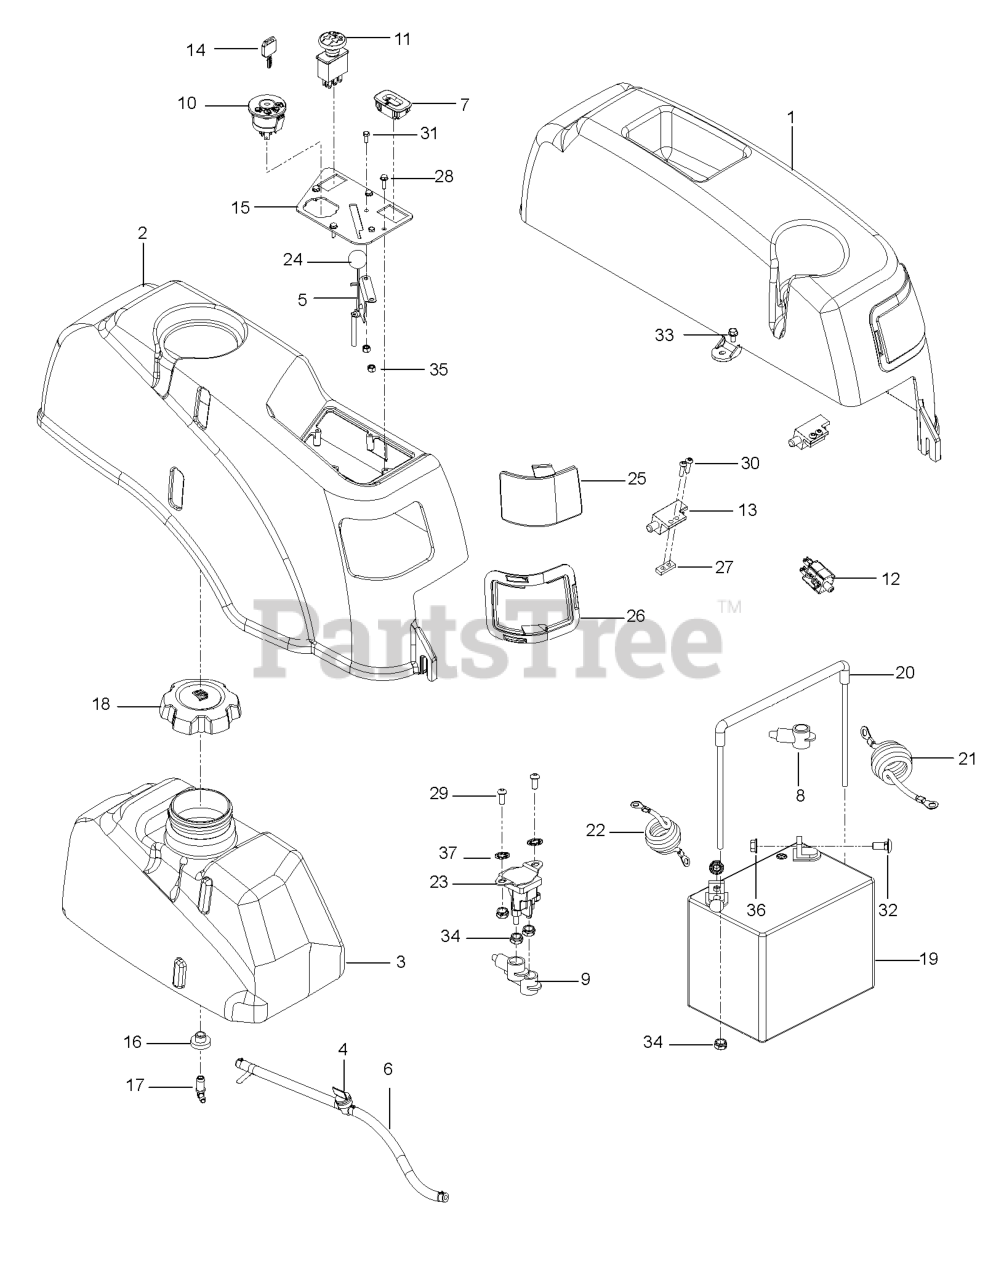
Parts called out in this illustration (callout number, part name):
1	FRAME WELDMENT, ORANGE
2	CHAIN COVER, ORANGE
3	BEARING SUPPORT, ORANGE
4	BUSHING, FLANGED
5	BEARING, FLANGED
6	HCS 5/16C X 3/4
7	HCS 5/16C X 1 1/4
8	NUT 5/16 NYLOC
9	OIL CAP, 3/8"
10	HCS 3/8C X 1 1/4 GR5
11	NUT 3/8-16 NYLOC
12	BUSHING RAKE
13	SCREW 5/16C X 1 HEX CAP
14	WASHER 5/16 FLAT
15	BOLT 1/4C X 1 3/4
16	SPRING PIN
17	SPRING, COMPRESSION
18	NUT.1/4-20.HEX.NYLOC.ZD
19	HCS 5/16C X 1
20	NUT 5/16C HEX
21	COVER, ORANGE
22	KNOB W/STUD
24	ZERK 1/8 NPT
25	NUT 5/16-18 HEX JAM ZD
26	KNOB, 5/16-18 NYLOC
27	SPROCKET, 21T W/SETSCREWS
28	SPROCKET, ENGINE
29	SPROCKET, IDLER #40 14 TOOTH
30	MOUNTING HUB
31	NUT 3/8C WHIZ
32	HCS 3/8-16 X 1 3/4 GR5
34	KEY 1/4 SQ X 3/4
35	KEY 7MM SQ X 33MM ENGINE
36	SCREW 5/16C X 1 SQ HEAD SET
37	WASHER 3/8 FLAT
38	SET SCREW 5/16 NYLOC
39	KEY 3/16 SQ X 1-1/4
40	CHAIN, TRANSMISSION #40
41	WASHER.LOCK.HVY.HLCL.SPR.5/16
42	HCS 5/16C X 1 3/4
43	HCS M5-0.8 X 16MM GR 8.8 ZD
44	NUT 5MM-.8 HEX ZD
45	CLAMP, THROTTLE CABLE
46	CLIP, THROTTLE HONDA
47	SCREW METRIC SPECIAL X 1/4 ZN
48	SPRING, THROTTLE, HONDA ENGINE
